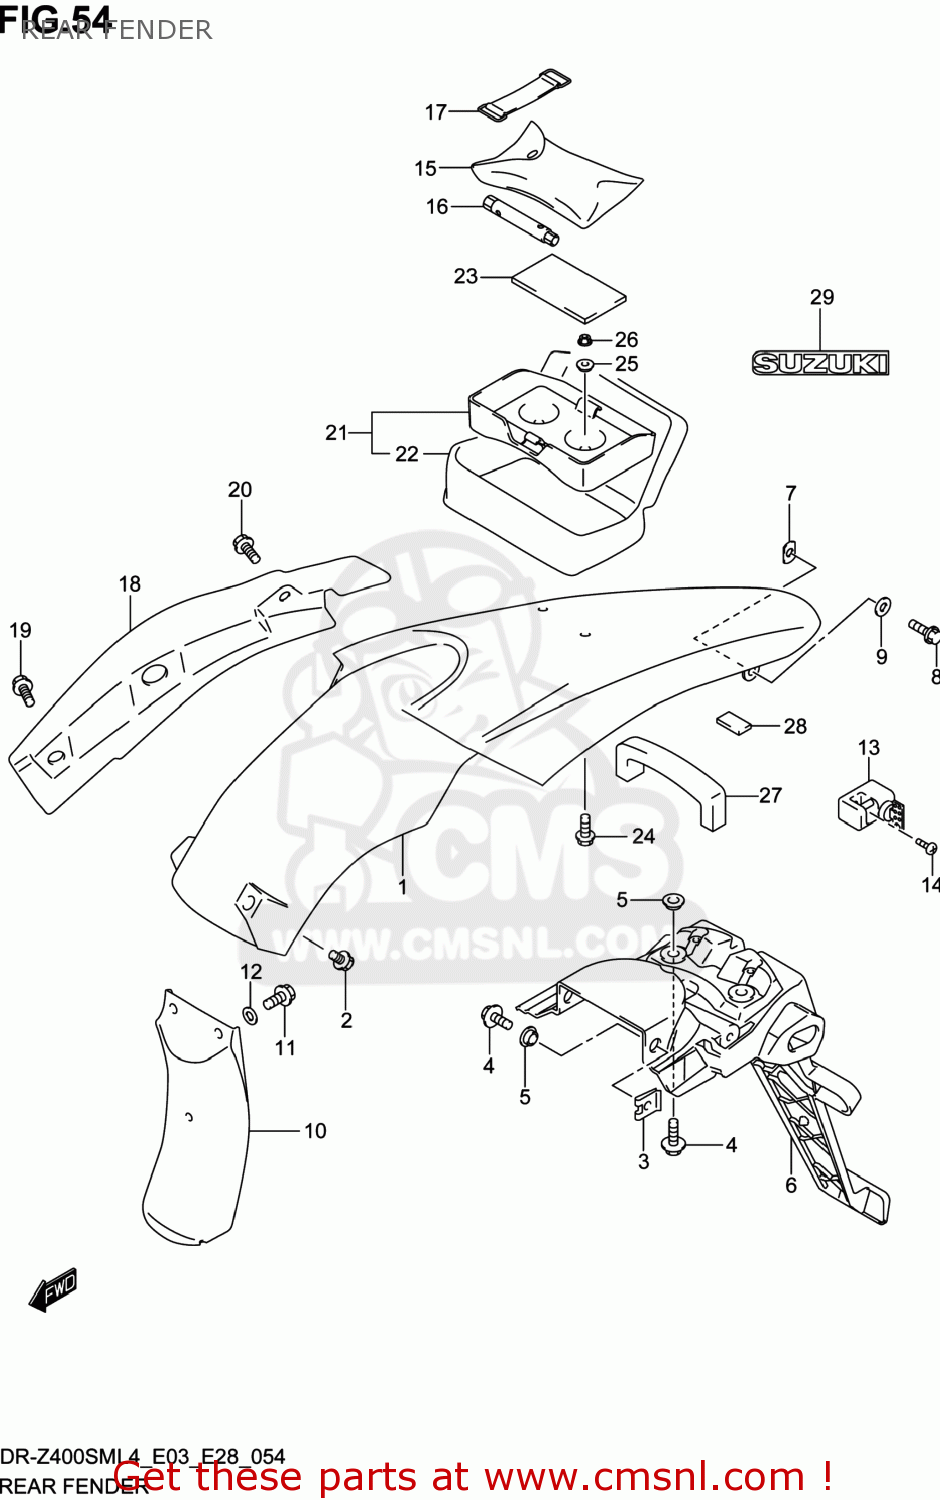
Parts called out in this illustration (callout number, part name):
1	FENDER,RR
2	BOLT(6X16)
3	PLATE,RR FENDER
4	BOLT(6X20)
5	WASHER
6	EXTENSION,RR FENDER
7	NUT,COWL
8	BOLT
9	WASHER
10	MUDGUARD,RR FENDER FR
11	BOLT
12	WASHER
13	LOCK SET,HELMET
14	SCREW(6X14)
15	TOOL ASSY
16	SPARK PLUG WRENCH(8X10)
17	BAND
18	MUDGUARD,RR FENDER,R
19	BOLT(6X18)
20	BOLT(6X12)
21	BAG ASSY,SEAT TAIL
22	BAG,SEAT TAIL
23	CUSHION,RR BAG
24	BOLT
25	WASHER
26	NUT
27	SEALER,SIDE COVER L
28	PROTECTOR(170X95X3.0)
29	EMBLEM,SUZUKI
